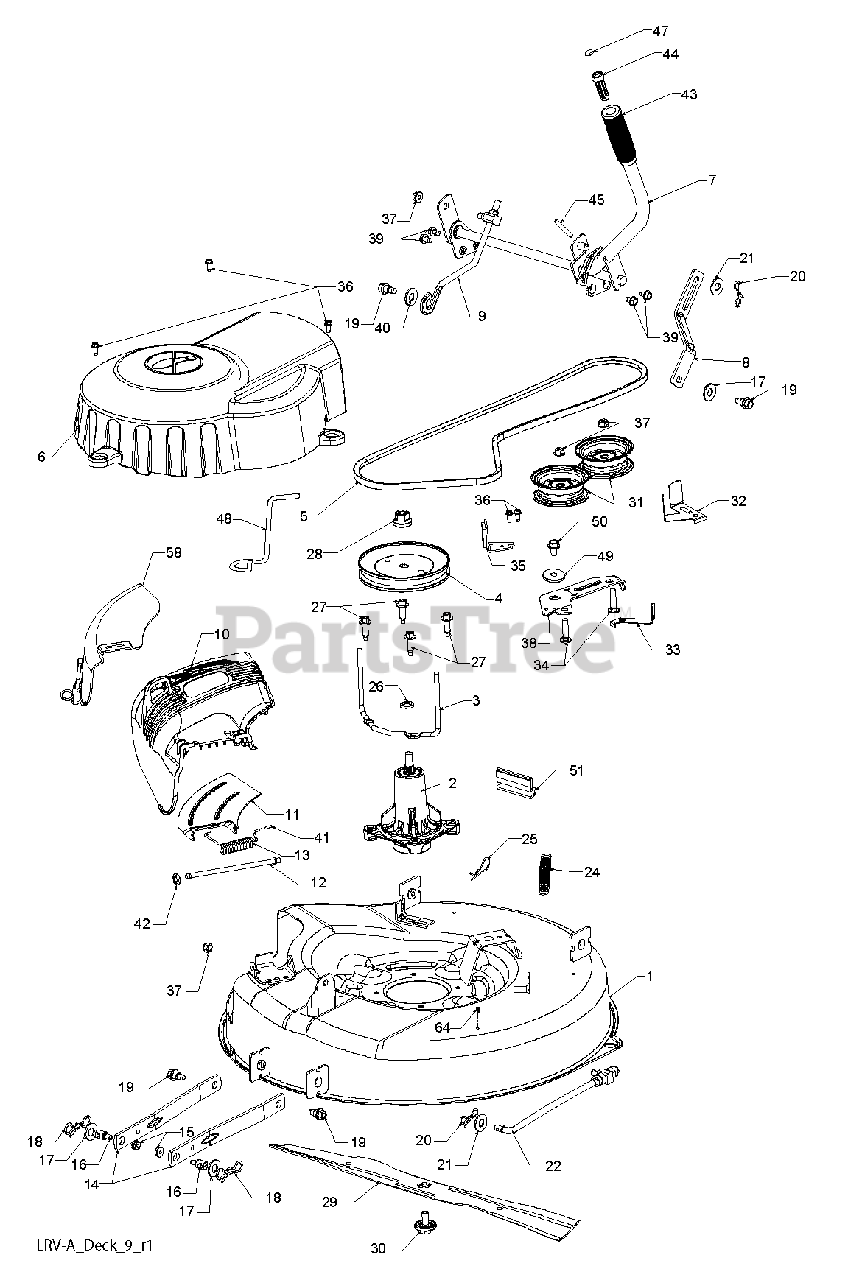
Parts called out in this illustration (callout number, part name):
1	DECK, 26"
2	MANDREL.ASM.SUB-NON.GR
3	KEEPER.BELT.MANDREL.PULLEY
4	PULLEY.MANDREL
6	COVER, MANDREL
7	LIFT.ASM.DECK.LRV
8	LINK, DECK LIFT
9	LINK.ASM.LIFT.ADJUSTABLE
11	SUPPORT, DEFLECTOR
12	ROD.HINGE
13	SPRING.TORSION.DEFLECT
14	ARMS.SUSP.MOWER.REAR.SRD
15	NUT LOCK HEX FLANGE 5/16-18
16	STUD.FASTNER.W/ANTI-ROTATE
17	WASHER.CLEAR.ZINC
18	PIN.COTTER.7/16.BOW TI.
19	BOLT.SHOULDER
20	PIN.COTTER.5/16.BOW TI
22	LINK.ASM.TOP.DECK.LRV
24	SPRING.EXTENSION.DECK.LRV
26	WASHER.SPACER.MANDREL
27	SCREW, WASHER HEAD
28	NUT.FLANGE.LOCK.TOP
29	BLADE.LRV.BAGGING
30	BOLT.WASHER.ASM.7/16-2
31	PULLEY.IDLER.48"PRIMARY
32	GUARD, BELT
33	KEEPER BELT
34	BOLT.3/8-16X1.50
35	ARM BRAKE MOWER RH
36	SCREW.1/4-20X5/8
37	NUT LOCK FLG 3/8-16 UNC
38	ARM, IDLER
39	SCREW LT
41	CAP-SLEEVE LT
42	NUT PUSH M
43	GRIP HANDLE
44	PLUNGER.ASM.LRV
45	PIN GROOVE.
47	PLUNGER BUT KIT
48	KEEPER.BELT
49	SPACER.RETAINER
50	SCREW 3/8-16X1
51	BUMPER.HOOD.TEX.HUSQVARNA
58	COVER.ASM.MULCH.26"LRV
64	SCREW 3/8-16X1/2
